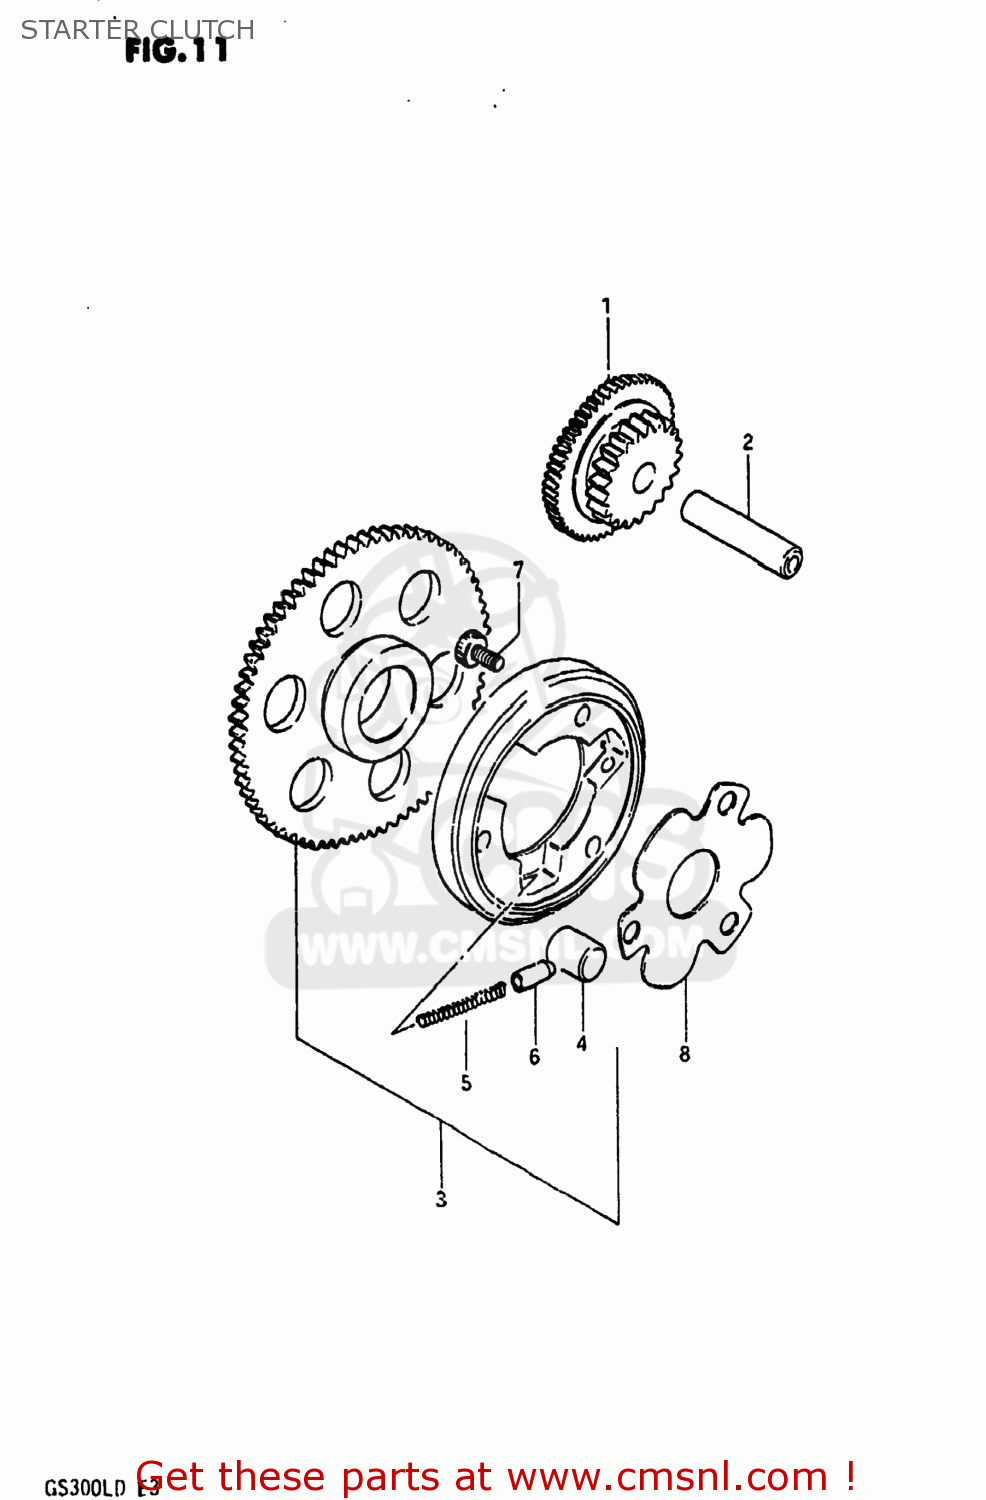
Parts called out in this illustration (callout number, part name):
1	GEAR,STARTER IDLE
2	PIN(7.4X13X40)
3	CLUTCH SET,STARTER
4	ROLLER(15X13)
5	SPRING
6	PIECE,PUSH
7	BOLT
8	SHIM,STARTER CLUTCH HUB
